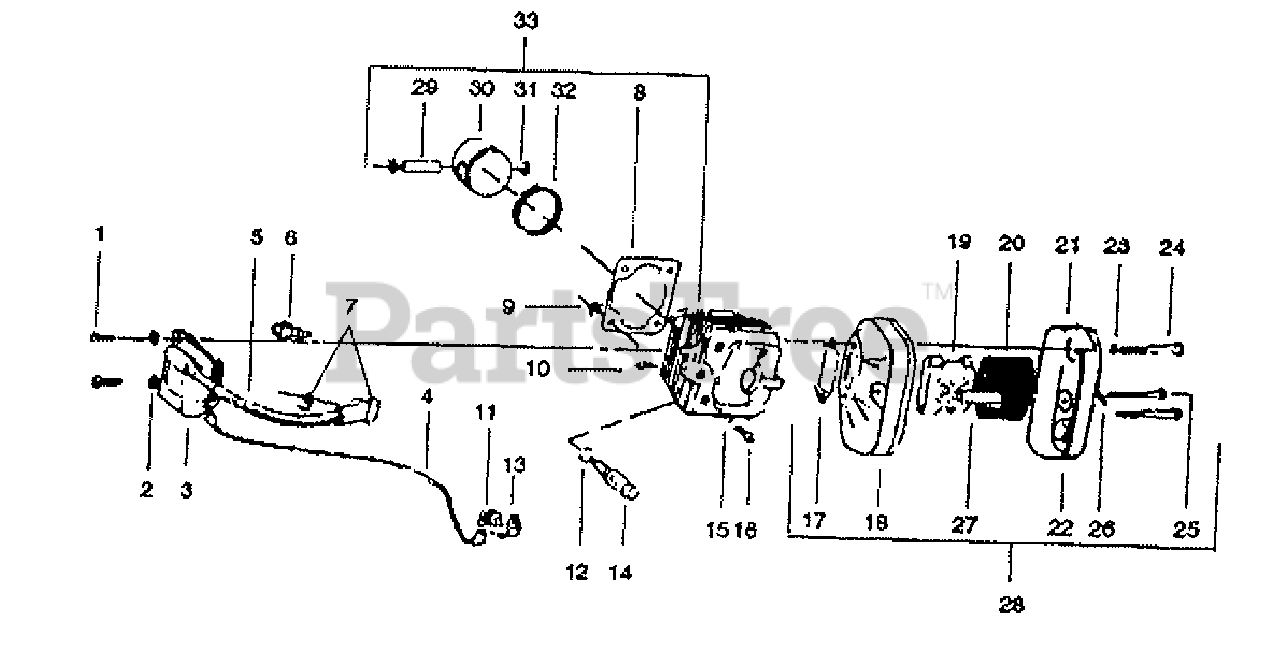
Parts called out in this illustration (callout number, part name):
3	Module & Switch Wire Ass'y.
4	Switch Wire
6	Spark Plug
7	Spark Plug Boot & Clip
8	Cylinder Base Gasket
11	Grounding Switch
13	Switch Plate
14	Decompression Valve
17	Muffler Gasket
18	Muffler Body
19	Meffler Channel
20	Muffler Screen
21	Muffler Cover Ass'y
22	Heat Shield Ass'y
23	Lockwasher
26	Lockwasher
27	Spacer
28	Muffler Ass'y
29	Wrist Pin
31	Retainer
32	Piston Ring Set
33	Cylinder & Piston Kit
